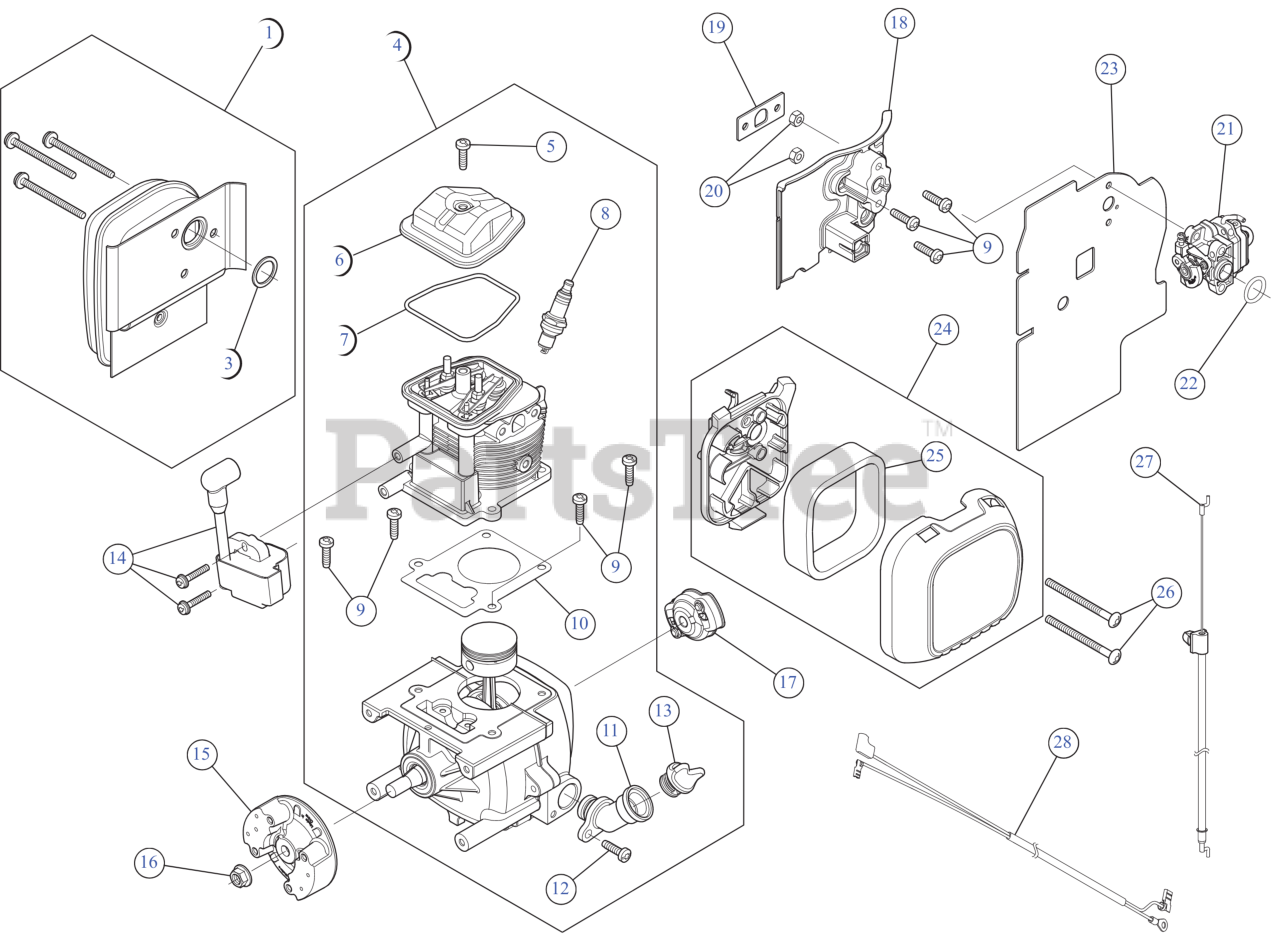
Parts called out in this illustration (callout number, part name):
1	MUFFLER ASSEMBLY AC4
3	MUFFLER GASKET
4	SHORT BLOCK
5	SCR, VALVE COVER
6	ROCKER COVER AC4
7	O-RING ROCKER CVR
8	SPARK PLUG 4 CYCL
9	SCREW, M5 x 18.7MM
10	CYLINDER GASKET
11	OIL TUBE ASSEMBLY AC4
12	SCR, M5 x 15.8MM
13	OIL PLUG ASSEMBLY
14	MODULE MA-95
15	FLYWHEEL ASSEMBLY
16	NUT 3/8-24
17	PAWL ASSEMBLY AC5
18	INSULATOR CARB
19	INSULATOR GASKET
20	NUT 10-32
21	CARBURETOR
23	CARB GASKET AC4
24	AIR CLEANER ASSEMBLY
25	AIR FILTER
26	SCREW 10-32X2.5
27	THROTTLE CABLE
28	LEAD WIRES
